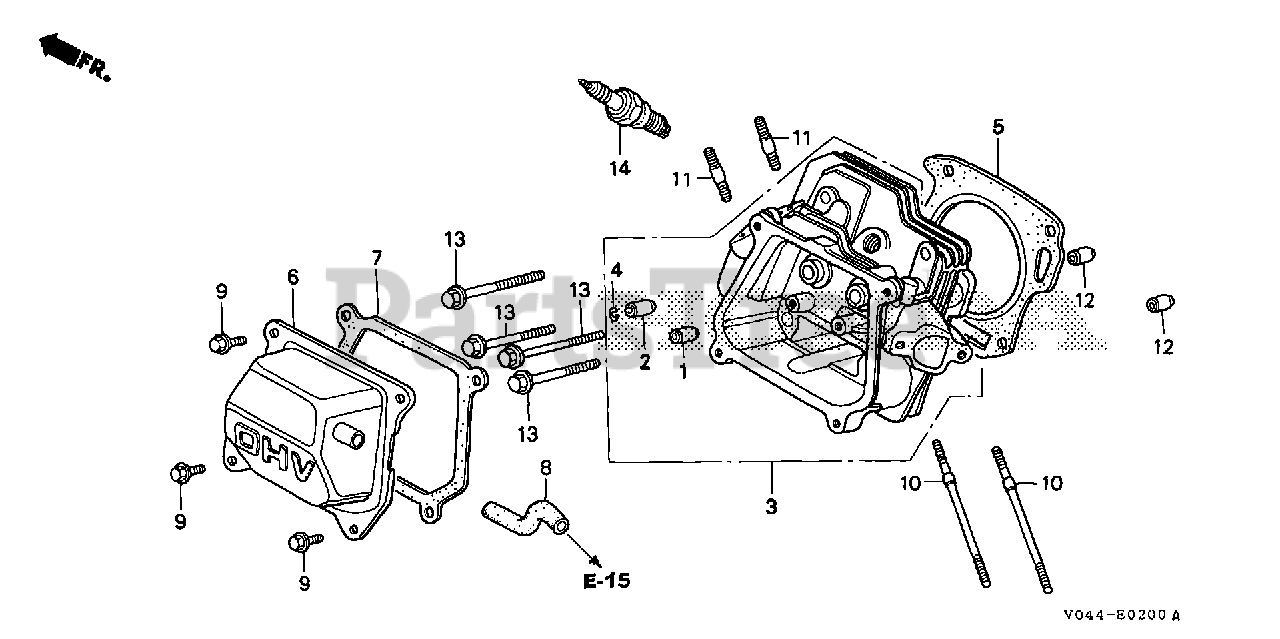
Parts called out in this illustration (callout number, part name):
1	GUIDE, VALVE (OVER SIZE)
2	GUIDE, EX. VALVE (OVER SIZE)
3	CYLINDER HEAD
4	CLIP, VALVE GUIDE
5	GASKET, CYLINDER HEAD (NIPPON LEAKLESS)
6	COVER, HEAD
7	GASKET, HEAD COVER
8	TUBE, BREATHER
9	BOLT, FLANGE (6X12) (CT200)
10	BOLT, STUD (6X112)
11	BOLT, STUD (8X32)
12	PIN, DOWEL (10X16)
13	BOLT, FLANGE (8X60)
14	SPARK PLUG (BPR5ES) (NGK)
14	SPARK PLUG (W16EPR-U) (DENSO)
